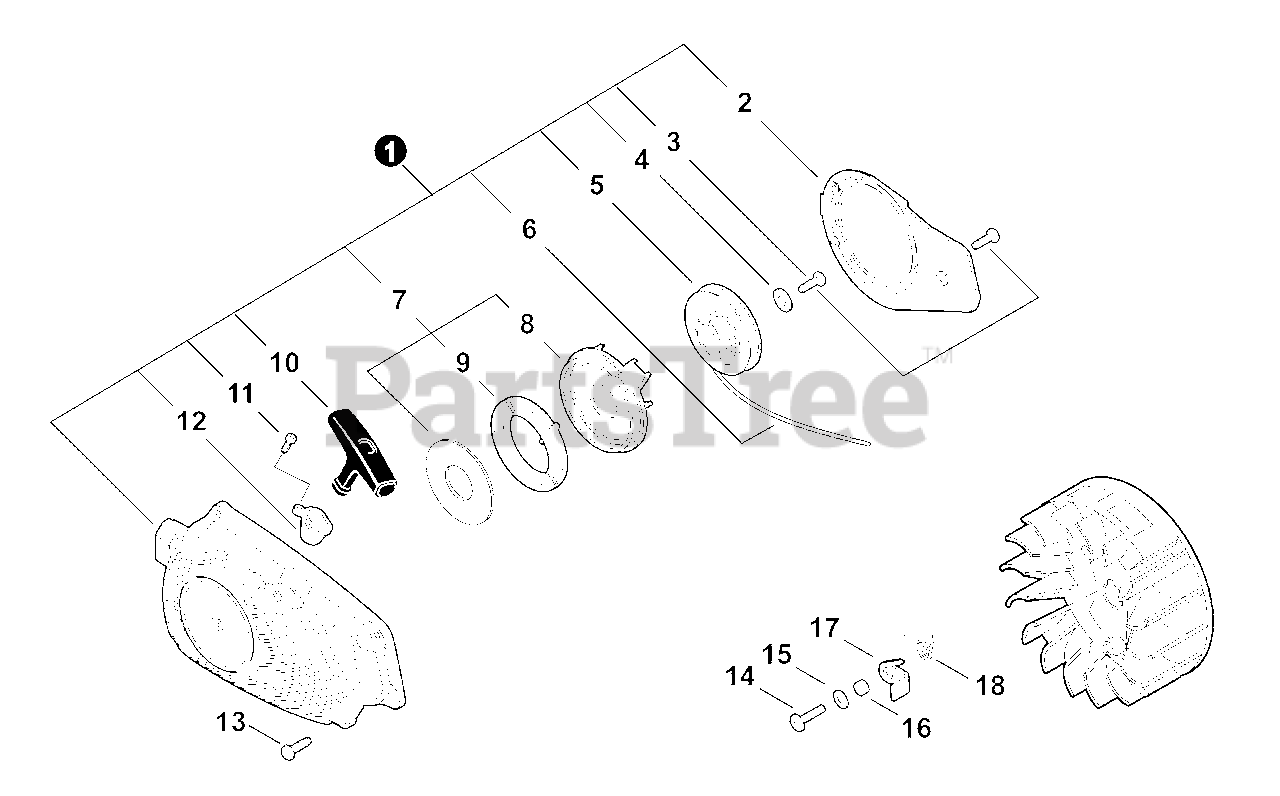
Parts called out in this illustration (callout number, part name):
1	STARTER ASSY
2	PLATE, GUIDE
3	SCREW 4×14
4	WASHER 4.1×15.5×1T
5	REEL, ROPE
6	ROPE, STARTER 3.0×850
7	SPRING KIT, RECOIL
8	PLATE, STARTER
9	SPRING, RECOIL
10	GRIP, STARTER
11	SCREW 3×14
12	GUIDE, ROPE
13	SCREW 4×16
14	SCREW 5×12
15	WASHER 5.5×12×0.8
16	SPACER 5.2×8×2.1
18	SPRING, TORSION
